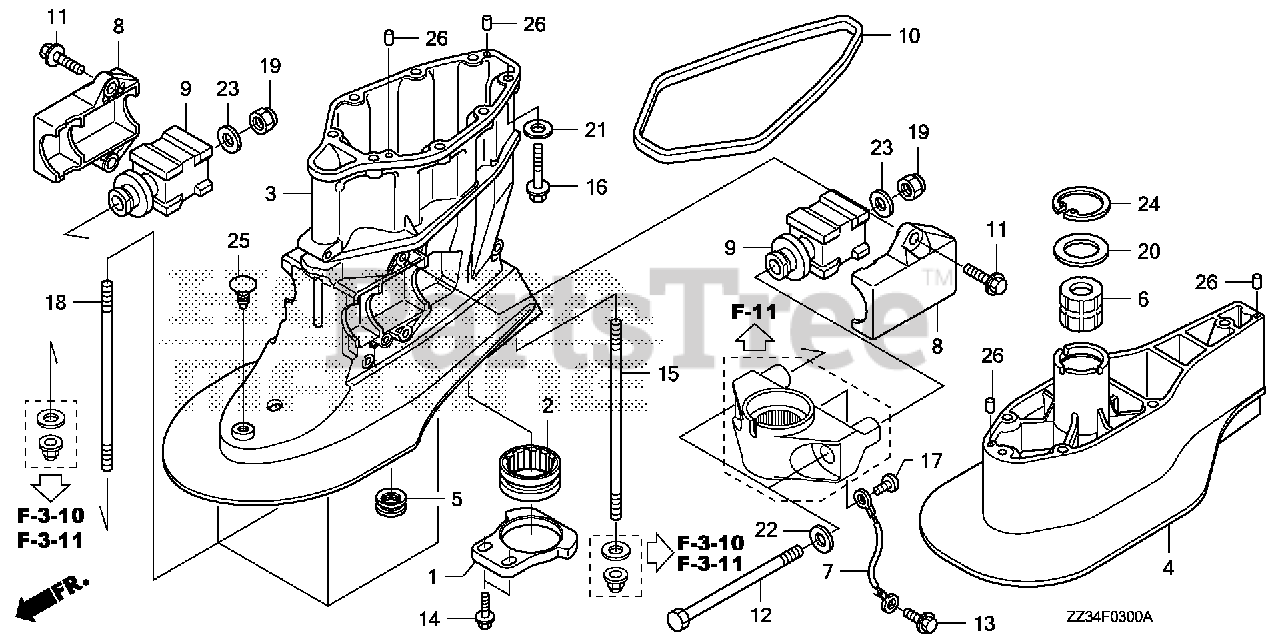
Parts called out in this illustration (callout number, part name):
1	HOLDER, EX. PIPE GROMMET
2	GROMMET, EX. PIPE
3	CASE, EXTENSION *NH282MU* (OYSTER SILVER METALLIC-U)
4	SEPARATOR, EXTENSION *NH282MU* (XL) (OYSTER SILVER METALLIC-U)
5	GROMMET, EXTENSION CASE
6	BUSH, VERTICAL SHAFT
7	WIRE, LEAD (1.5X116MM)
8	HOUSING, MOUNTING (LOWER)
9	MOUNT, RUBBER (LOWER)
10	SEAL B, COVER (LOWER)
11	BOLT, FLANGE (8X25)
12	BOLT, HEX. (12X186)
13	BOLT, FLANGE (6X12)
14	BOLT, FLANGE (6X20)
15	BOLT, STUD (10X202)
16	BOLT, FLANGE (8X35)
17	SCREW, PAN (6X8)
18	BOLT, STUD (10X164)
19	NUT, SELF-LOCK (12MM)
20	WASHER (26MM)
21	WASHER, PLAIN (8MM)
22	WASHER, PLAIN (12MM)
23	WASHER, PLAIN (12MM)
24	CIRCLIP (INNER) (40)
25	CLIP (7MM)
26	PIN, DOWEL (6X10)
